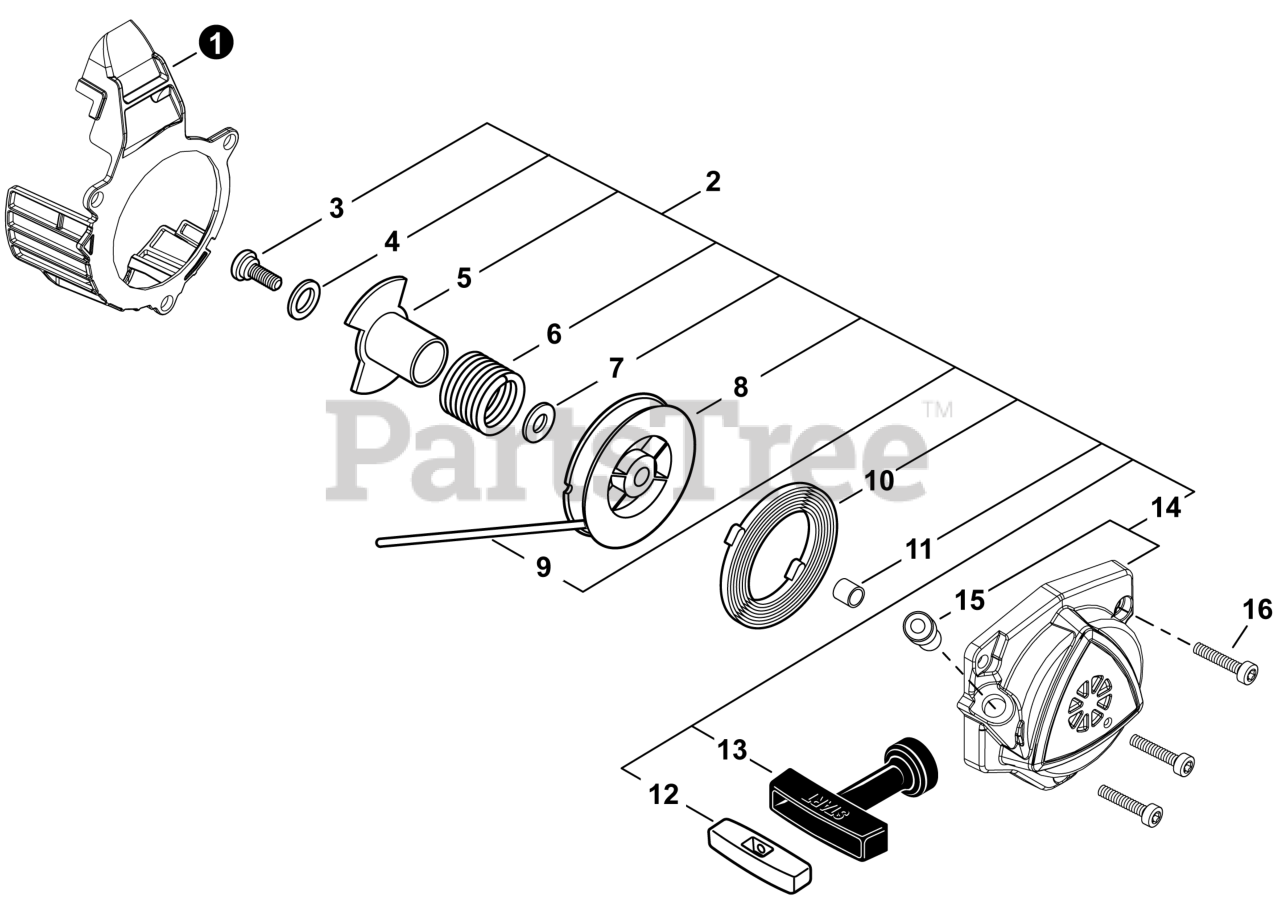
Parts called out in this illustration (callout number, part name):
1	GUARD, DEBRIS
2	STARTER ASSY, RECOIL
3	SCREW 5
4	WASHER, THRUST
5	PLATE, FRICTION
6	SPRING, FRICTION
7	WASHER 19.7
8	REEL, ROPE
9	ROPE, STARTER
10	SPRING, SPIRAL
12	RETAINER, ROPE
13	GRIP, STARTER
14	CASE, STARTER
15	GUIDE, ROPE
16	BOLT 5x20
